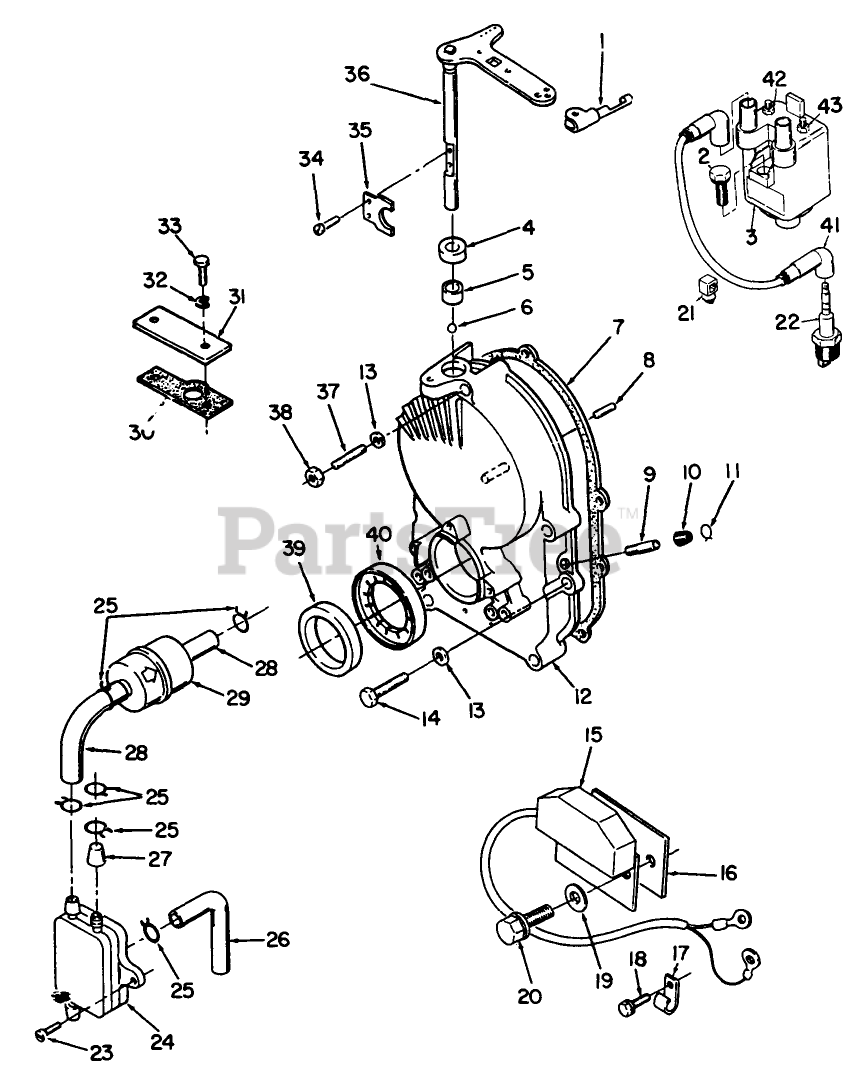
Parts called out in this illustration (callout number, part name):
2	SCREW-HH
3	COIL-BATTERY IGNITION
5	BEARING
7	GEAR CASE MTG GASKET
8	PIN-DOWEL
9	TUBE-PORT, VACUUM
10	CAP-FUEL OUTLET
11	CLAMP
12	Kit-Gearcase (Incl. Ref. #4-6, 8-11, 26, & 34-36)
13	WASHER
14	SCREW-HH
15	CONTROL-IGNITION
16	INSULATOR-IGN MODULE
17	CLIP-WIRE
18	SCREW-HH
19	WASHER-LOCK, INT
20	SCREW-HH
21	WIRE ROUTING CLIP
22	SPARK PLUG
23	SCREW-TAPPING PAN HD
24	PUMP-FUEL
25	CLAMP
26	HOSE-VACUUM
27	CAP-FUEL OUTLET
28	Hose
29	FILTER-FUEL
30	GASKET
31	PLATE-COVER
32	WASHER-FLAT
33	SCREW-HH
34	Screw
36	SHAFT/ARM-GOVERNOR
37	STUD-GEAR COVER
38	NUT-HEX
39	Seal-Oil
40	ROTOR-IGNITION
41	Cable Plug 9" Long
42	NUT-HEX FLANGE
43	NUT-HEX FLANGE
